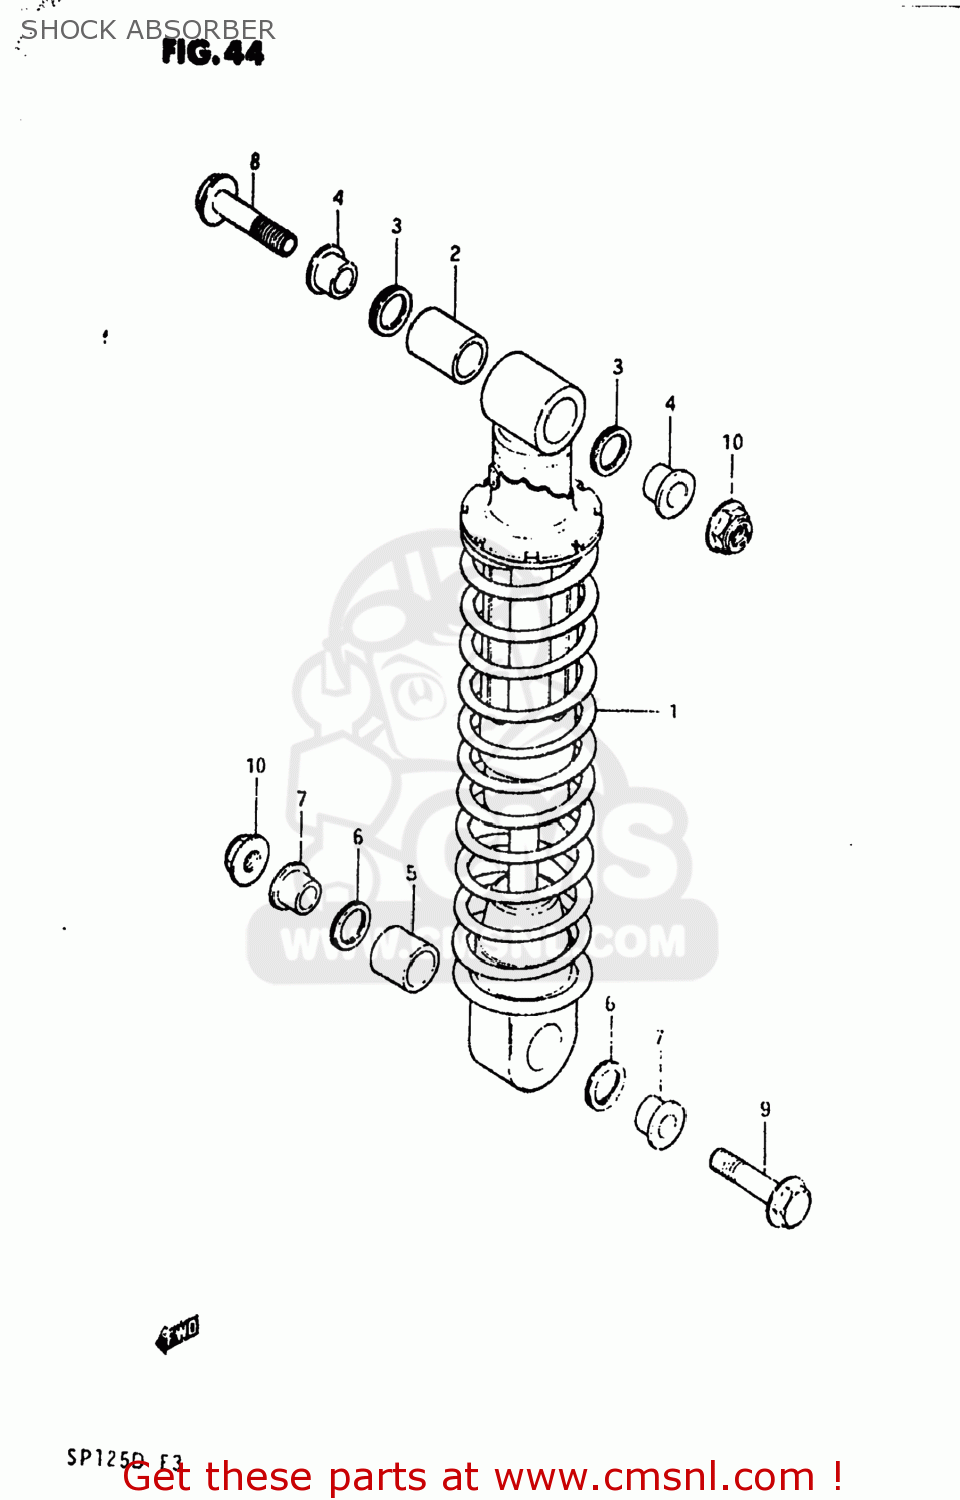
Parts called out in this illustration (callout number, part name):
1	ABSORBER ASSEMBLY,REAR SHOCK
2	BUSH,UPR
3	DUST SEAL,LEVER CUSHION UNIT
4	COLLAR,UPR
5	BUSH,LEVER CUSHION UNIT
6	DUST SEAL,LEVER CUSHION UNIT
7	SPACER,LEVER CUSHION UNIT
8	BOLT(10X60)
9	BOLT(10X50)
10	NUT
